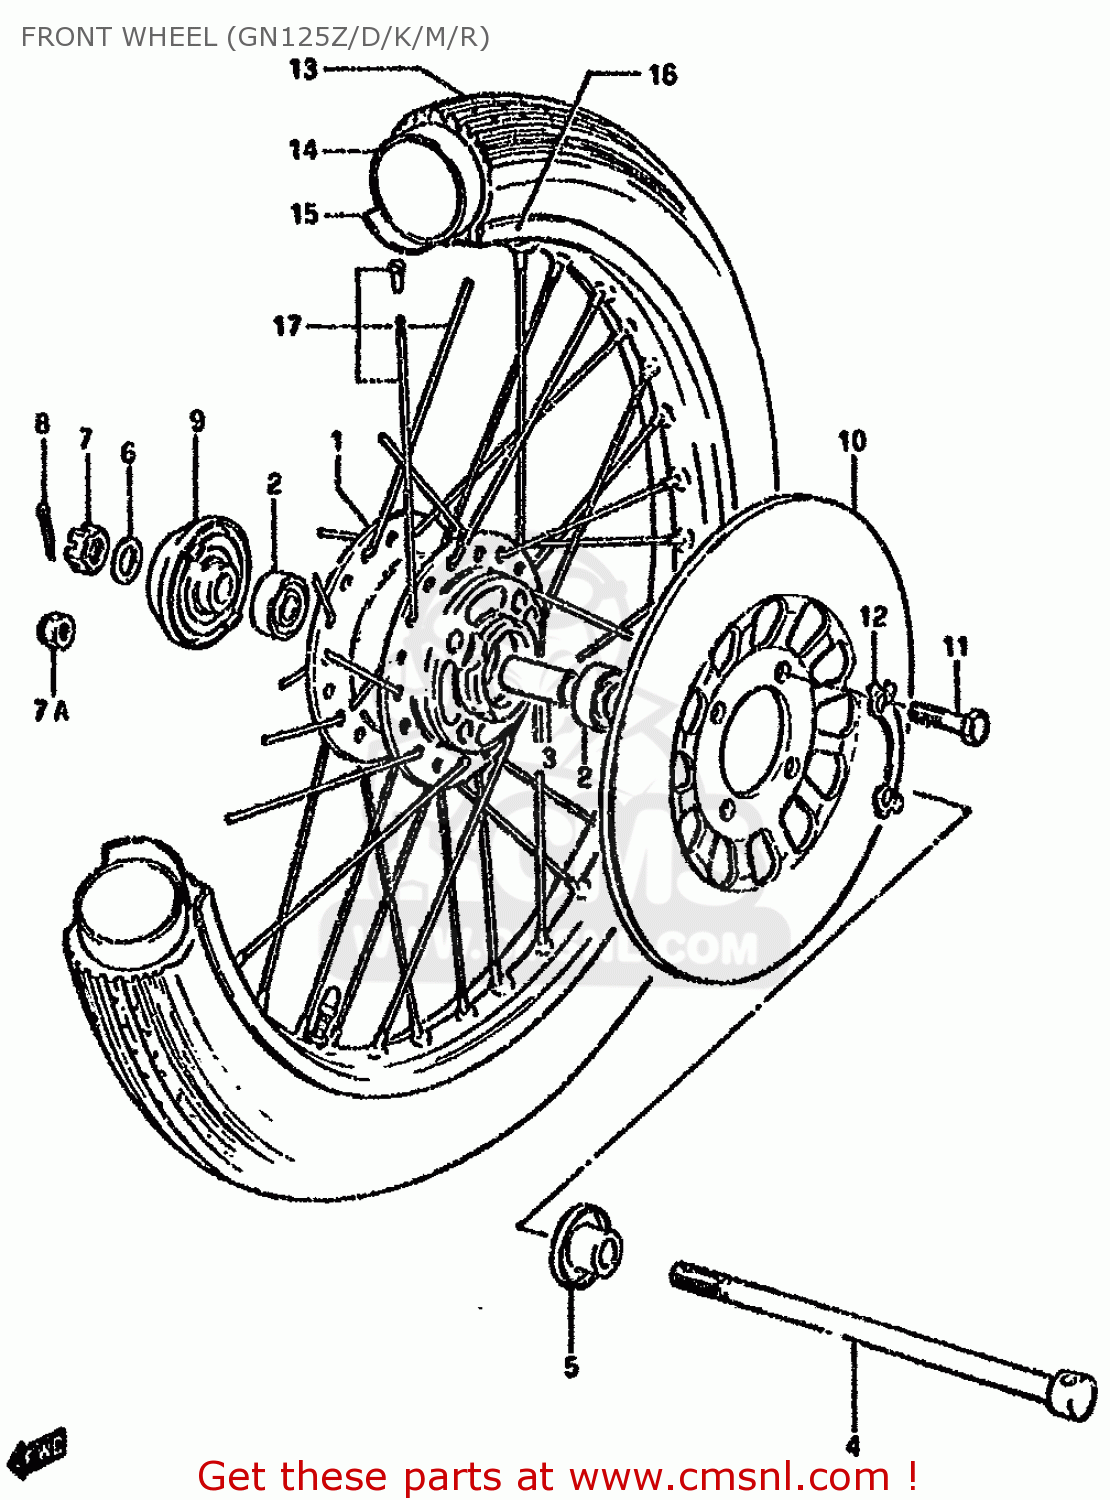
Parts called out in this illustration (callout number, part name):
1	HUB,FRONT
2	BEARING
3	SPACER (12.6X19X52)
4	AXLE,FR
5	SPACER,FR AXLE,L
6	WASHER
7	NUT
7A	NUT 12MM
8	COTTER PIN
9	BOX ASSY,SPEEDOMETER GEAR
10	DISC,FR BRAKE
11	BOLT(8X30)
12	WASHER
13	TIRE,FRONT
14	TUBE,INNER
15	PROTECTOR,INNER TUBE
16	RIM,FR WHEEL
17	SPOKE ASSY,FR
